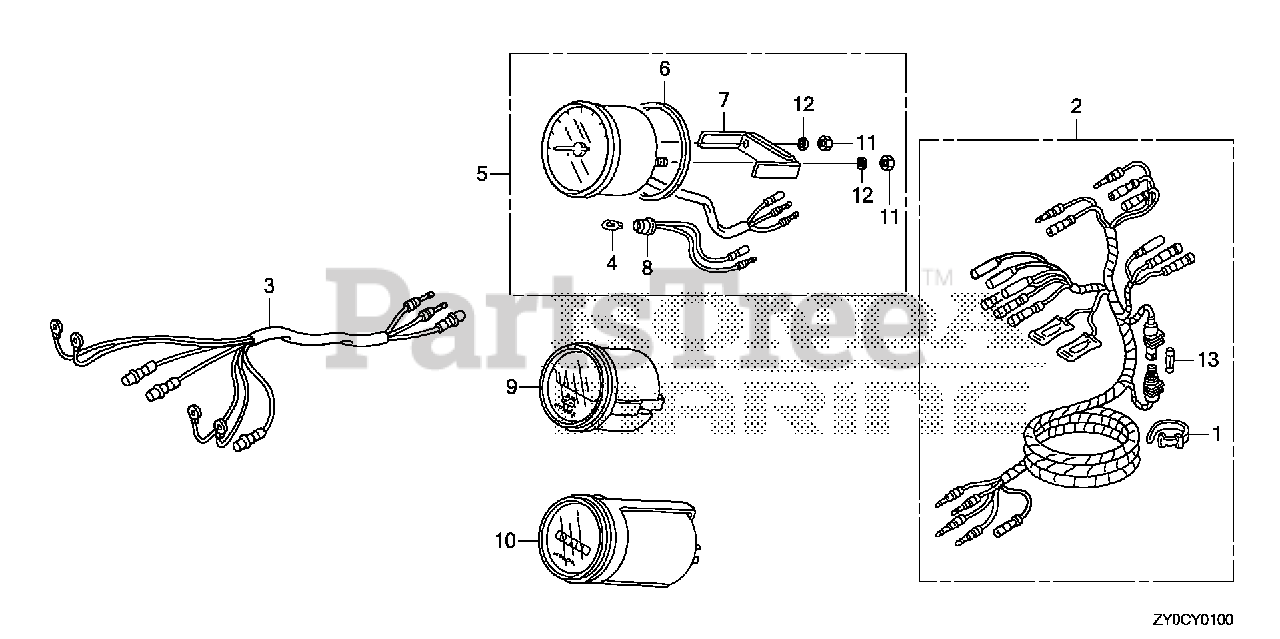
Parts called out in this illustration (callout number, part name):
1	BAND B1, CABLE Use up to Frame SN 1001879.
2	HARNESS ASSY., METER (A)
3	HARNESS ASSY., METER (B)
4	BULB, WEDGE BASE (T10) (12V 1.7W) (STANLEY)
5	TACHOMETER ASSY.
6	GASKET
7	BRACKET (TO 1015209) (FROM 1015210)
8	SOCKET (TO 1015209) (FROM 1015210)
9	METER ASSY., VOLT
10	METER ASSY., HOUR L.C.D.
11	NUT, HEX. (5MM)
12	WASHER, SPRING (5MM)
13	FUSE A (10A)
